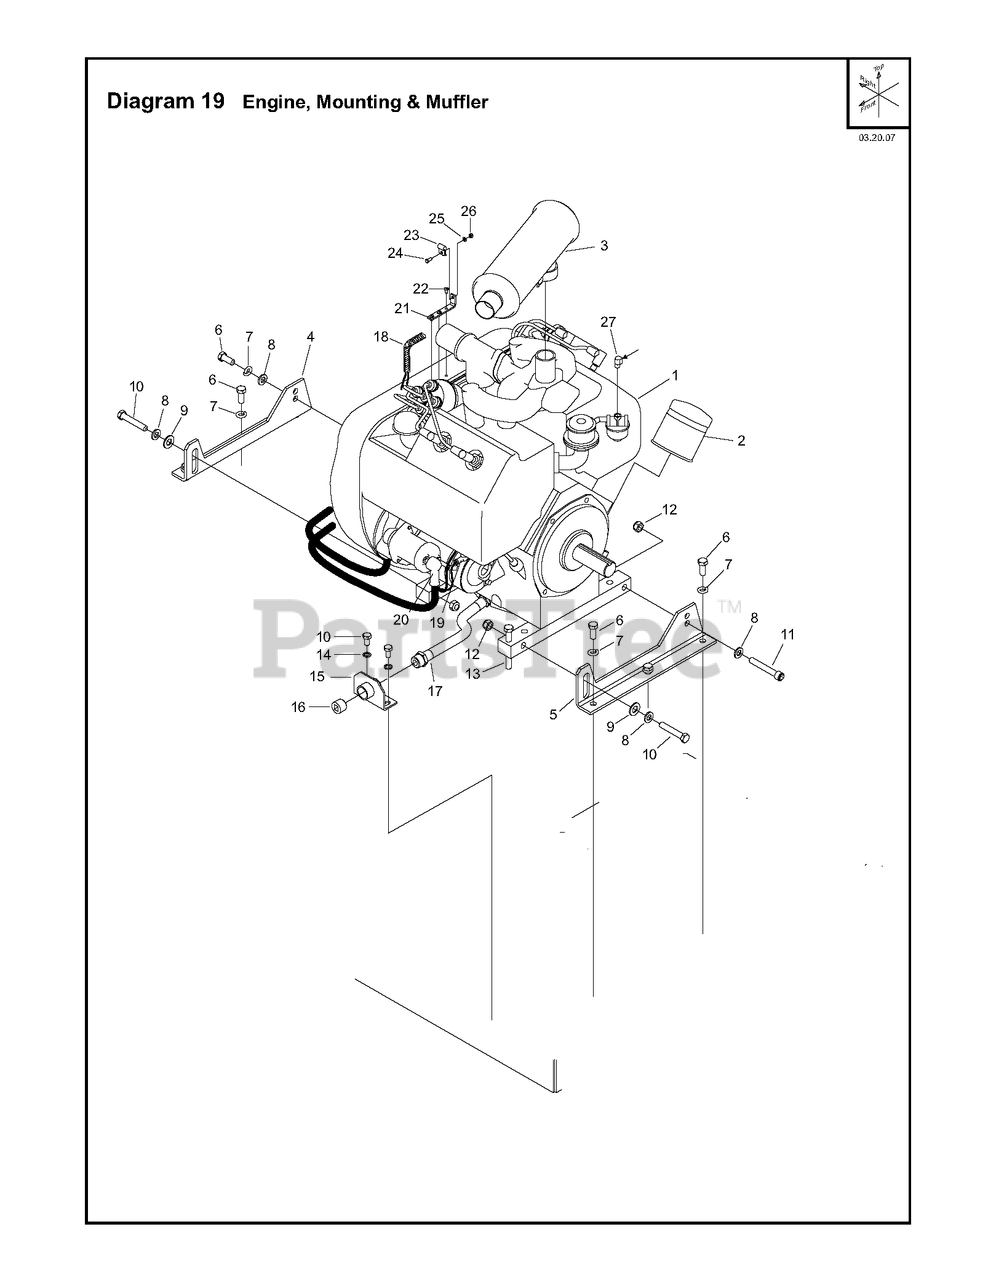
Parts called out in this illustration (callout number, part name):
4	BRACKET. ENGINE BASE RH. BLACK
5	BRACKET. ENGINE BASE LH PTD
6	HHCS. M12 x 1.75 x 30 DIN933ZP
7	LOCKWASHER. SPLIT .5 Z/P
8	WASHER
10	HHCS. M10 x 1.5 x 20 DIN933 ZP
11	SHCS. M12 x 1.75 x 80mm GR12.9
12	LOCKNUT. FIBER M12 DIN 985 Z/P
13	HHCS M12x1.75x100 DIN 933ZP
14	LOCKWASHER. EXTERNAL STAR M10
15	WATER PUMP BRACKET - PTD BLK
18	WIRE HARNESS: PRO 35III
19	RUBBER BOOT. CABLE TERM./BLACK
21	BKT. MTG THROTTLE PTD BLK
22	BHSTS. 10 x .375 Z/P
24	HHCS. M5 x 0.8 x 16 DIN933 Z/P
25	WASHER
26	HEXAGON LOCKING NUT
27	STREET ELBOW 1/8 X 90DEG BRASS
